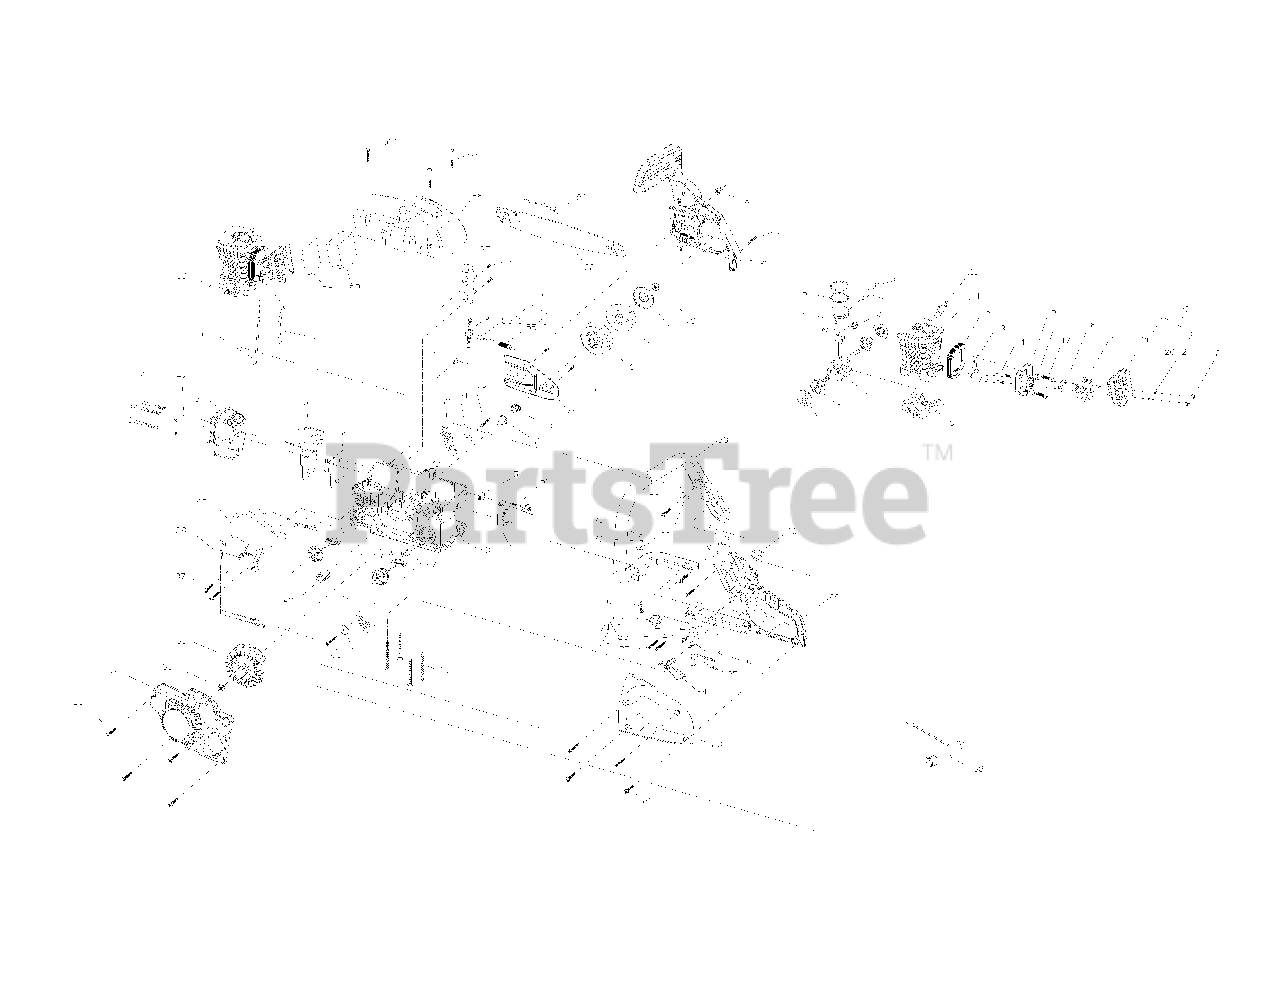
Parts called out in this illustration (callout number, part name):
1	CAP, BEARING
3	CRANK/ROD ASS'Y
5	RING, PISTON
6	ROLLER, PISTON
7	PIN, PISTON
9	CASE, CRANK
10	SPARK PLUG
12	RUBBER, ISOLATOR
15	ISOLATOR, CARBURETOR
16	SPRING WASHER
19	CARBURETOR
20	AIR FILTER ASS/Y
23	HANDLE, LEFT PART
24	TRIGGER, THROTTLE
25	TRIGGER, RELEASE
29	HANDLE, REAR
31	WASHER
33	HANDLE, FRONT
34	STARTER HOUSING ASS'Y
38	WIRE ASS'Y
39	IGNITION ASS'Y
40	CONDUCTIVE PLATE
41	OIL CAP ASS'Y
42	FIX PLATE
44	FUEL CAP ASS'Y
45	FIX PLATE
48	HOUSING ASS'Y
49	HOLDER, CABLE
50	LEVER, CHOKE (MTD BLUE)
51	HOLDER, CHOKE LEVEL
52	FIX PLATE
53	CONNECTOR
55	PUMP ASS'Y
59	MUFFLER ASS'Y
61	CABLE, THROTTLE
62	FUEL PIPE
63	WOODRUFF KEY
65	FILTER, AIR
67	SCREW
70	SPRING WASHER
74	CAP, ANTI-DUST
76	DRUM ASS'Y
77	CLUTCH ASS'Y
78	CAP, ANTI-DUST
80	BRAKE KIT ASS'Y
83	CHAIN
86	SCREW
87	SPIKED BUMPER
